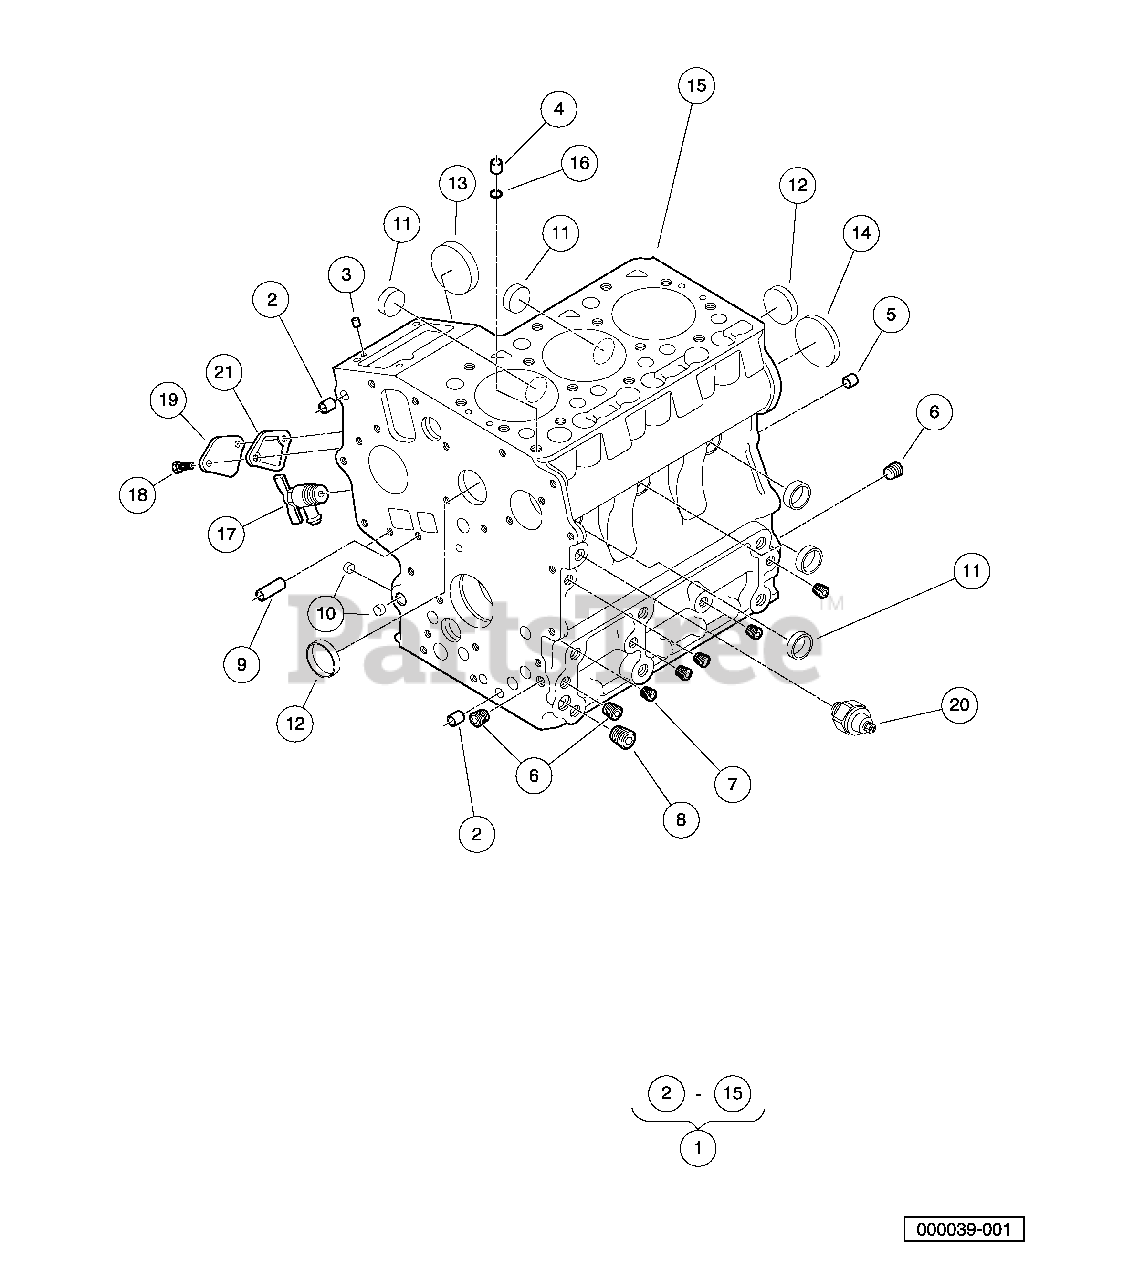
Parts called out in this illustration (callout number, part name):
1	Engine Block
2	Pin, Pipe, Dia 8 X 14
3	Pin, Straight, Dia 5 X 10
4	Pin, Pipe, Dia 7 X 14
5	Pin, Straight, Dia 8 X 16
6	Plug, 1/8"
7	Plug, 3/32"
8	Plug, 1/4"
9	Pin, Pipe, Dia 8 X 11
10	Cap, Sealing, Small
11	Cap, Sealing, Med
12	Cap, Sealing, Large
13	Cover, Fuel Camshaft
14	Plug, Expansion
15	Block, Engine
16	O Ring, 8 X 7
17	Cock, Drain
18	Bolt, M6 X 1 X 20
19	Plate, Engine Block
20	Switch, Oil Pressure
21	Gasket, Fuel Pump, D722
